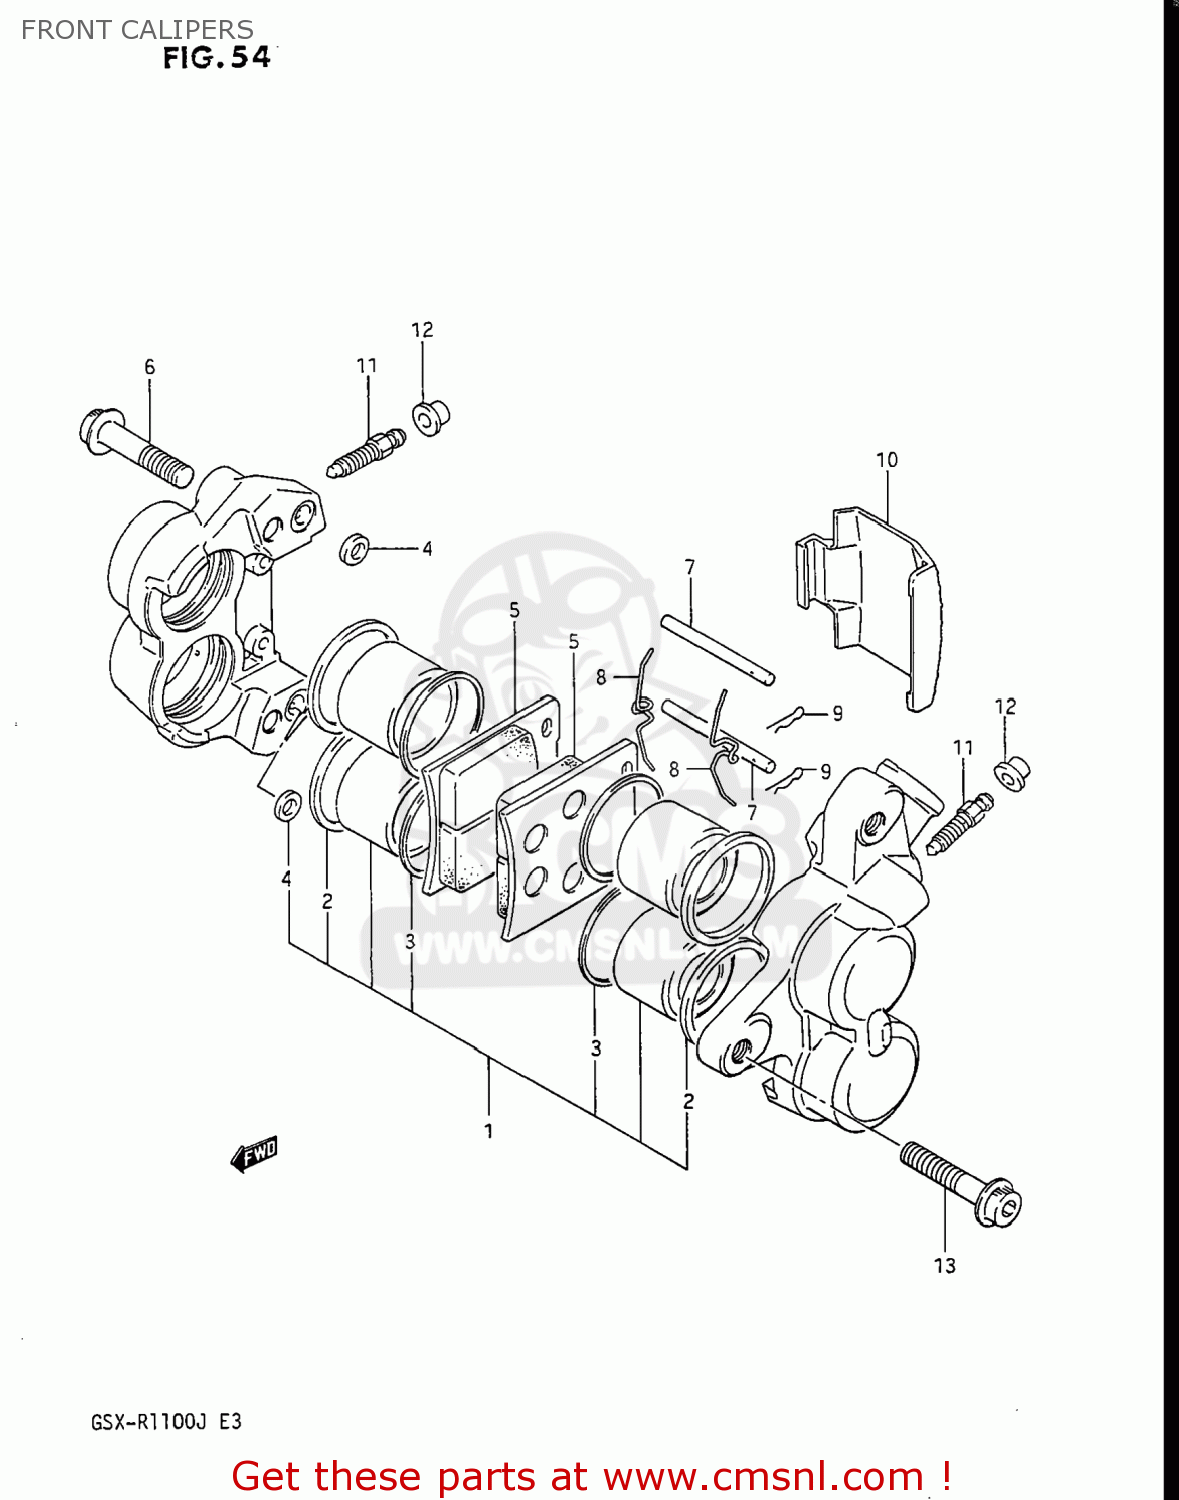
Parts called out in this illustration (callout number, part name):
1	PISTON SET
2	SEAL,PISTON
3	SEAL,WIPER
4	SEAL,JOINT
5	PAD
6	BOLT,HOUSING
7	PIN,PAD
8	SPRING
9	CLIP,PAD PIN
10	COVER,CALIPER
11	BLEEDER
12	CAP,BREATHER
13	BOLT
